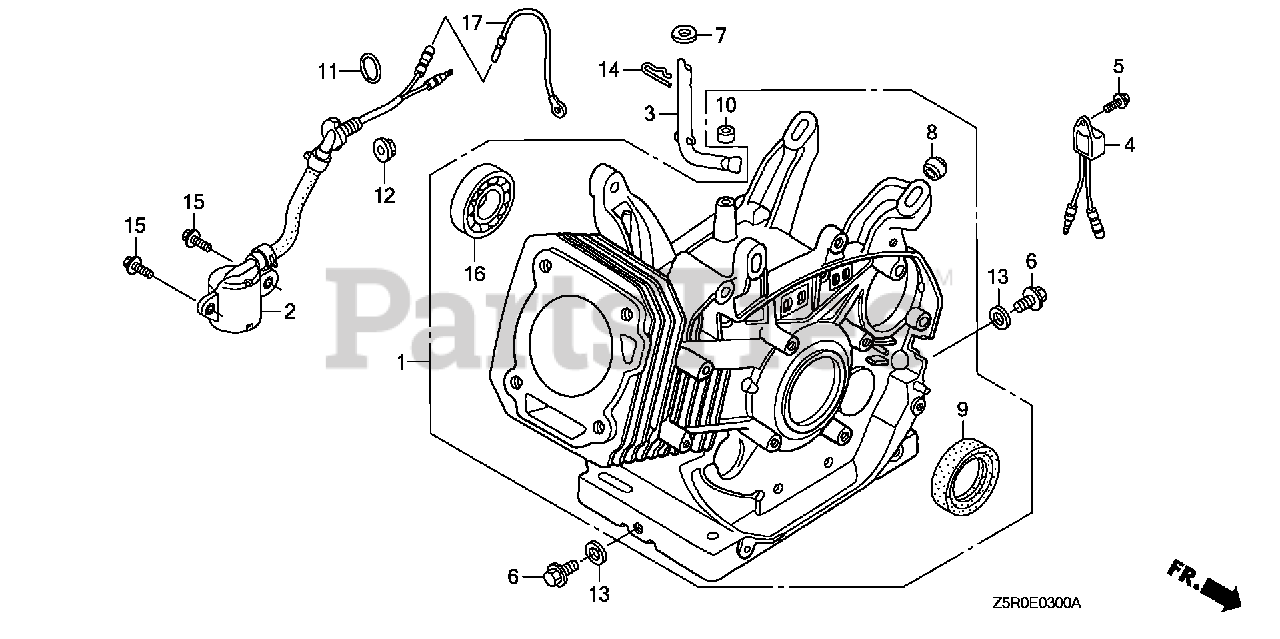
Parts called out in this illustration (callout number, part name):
1	CYLINDER ASSY. (ALERT)
2	SWITCH ASSY., OIL LEVEL
3	SHAFT, GOVERNOR ARM
4	ALERT UNIT, OIL
5	BOLT, FLANGE (6X12) (CT200)
6	BOLT, DRAIN PLUG (12X15)
7	WASHER (8.2X17X0.8)
9	OIL SEAL (35X52X8)
10	OIL SEAL (8X14X5)
11	O-RING (13.5X1.5) (ARAI)
11	O-RING (14MM) (NOK)
12	NUT, FLANGE (10MM)
13	WASHER, DRAIN PLUG (12MM)
14	PIN, LOCK (10MM)
15	BOLT, FLANGE (6X12)
16	BEARING, RADIAL BALL (6202)
